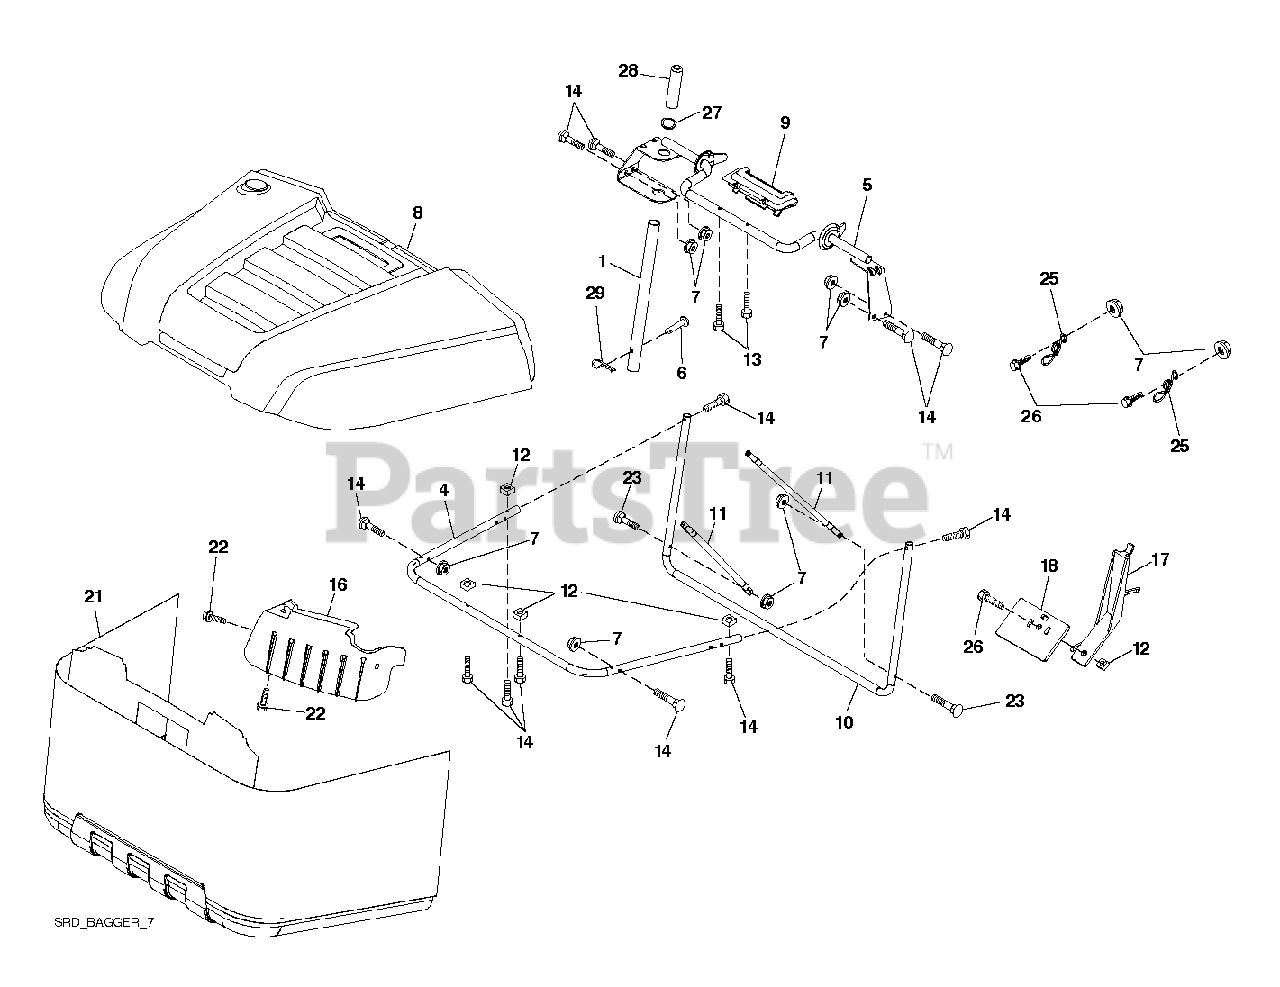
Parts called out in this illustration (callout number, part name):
1	TUBE.HANDLE.BAGGER.CRD/SRD.BLA
4	SUBASM.TOP.TUBE.TEX.CRD
5	FRAME.ASM.TOP.BAGGER.SRD
6	RIVET,DRILLED
7	NUT T
8	COVER.BAGGER.SRD.APPLI
9	INSERT.HANDLE.BAGGER.(2 2)
10	FRAME.FRONT.SRD.BAGGER
11	TUBING.BRACE.BAGGER.SRD.BLACK
12	NUT.SQUARE.1/4
13	SCREW.1/4X1.150.HXWSH
14	BOLT.SHOULDER.HX.WSH.1/4X1.150
16	DEFLECTOR.BAGGER.SRD
17	LEVER.BAGGER.FULL.SRD.BLACK
18	PADDLE.BAGGER.FULL.SRD.BLACK
21	BAG.ASM.BAGGER.SRD.HUSQVA.GREY
22	SCREW.HI-LO.CONSOLE
25	SPRING.LATCH.BAGGER.SRD
26	SCREW HEX CRT
27	RB GROMMET.RUBBER.SRD
28	GRIP.HANDLE.BLACK
29	PIN.COTTER.5/16.BOW TI
